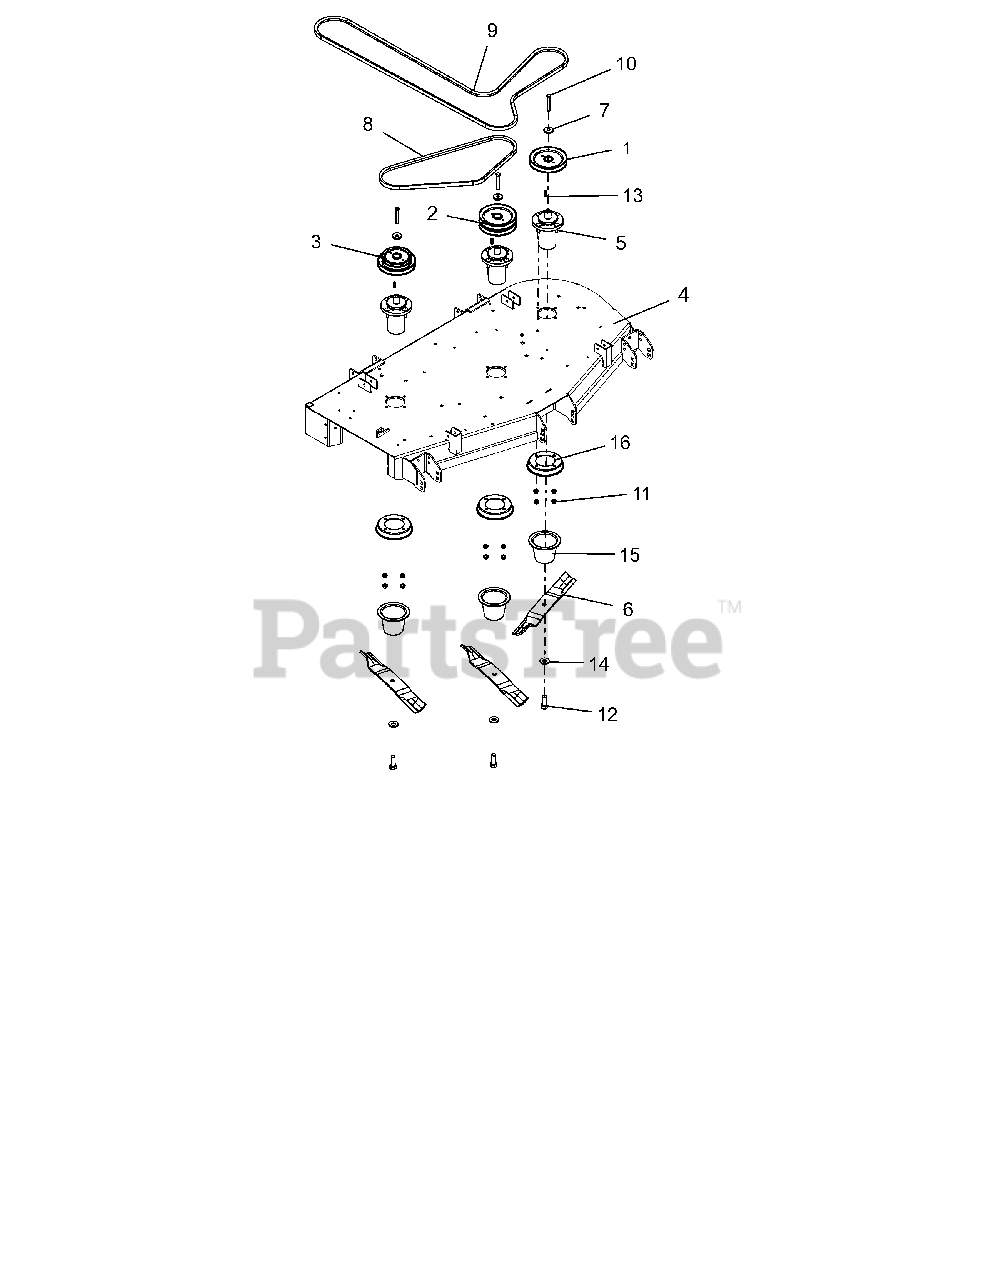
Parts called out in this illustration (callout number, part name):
1	PULLEY, SINGLE-1"ID X 6" OD
2	PULLEY, DOUBLE
3	PULLEY, DBL-1"IDX6.00"&4.75"OD
4	52"SIDE DISCH DECK WMT W/SAFE
5	ASM, MAINT FREE ALUM SPINDLE
6	BLADE, 18.00" MOWER (HI-LIFT)
7	RETAINER, SHEAVE
8	V-BELT, B-COGGED
9	V-BELT, HB RAW EDGE EPDM
10	BLT-HEX .38-16X2.75 GR8 YWZC
11	NUT-LK-CTR-FLG .38-16 YWZC
12	BLT-HEX .62-18X1.75 GR8 YWZC
13	KEY, SQ .25X.25X1.00 RC 40-50
14	WSHR-BLVL .669X1.535X.138
15	GUARD, SPINDLE LOWER
16	GUARD, SPINDLE TOP
